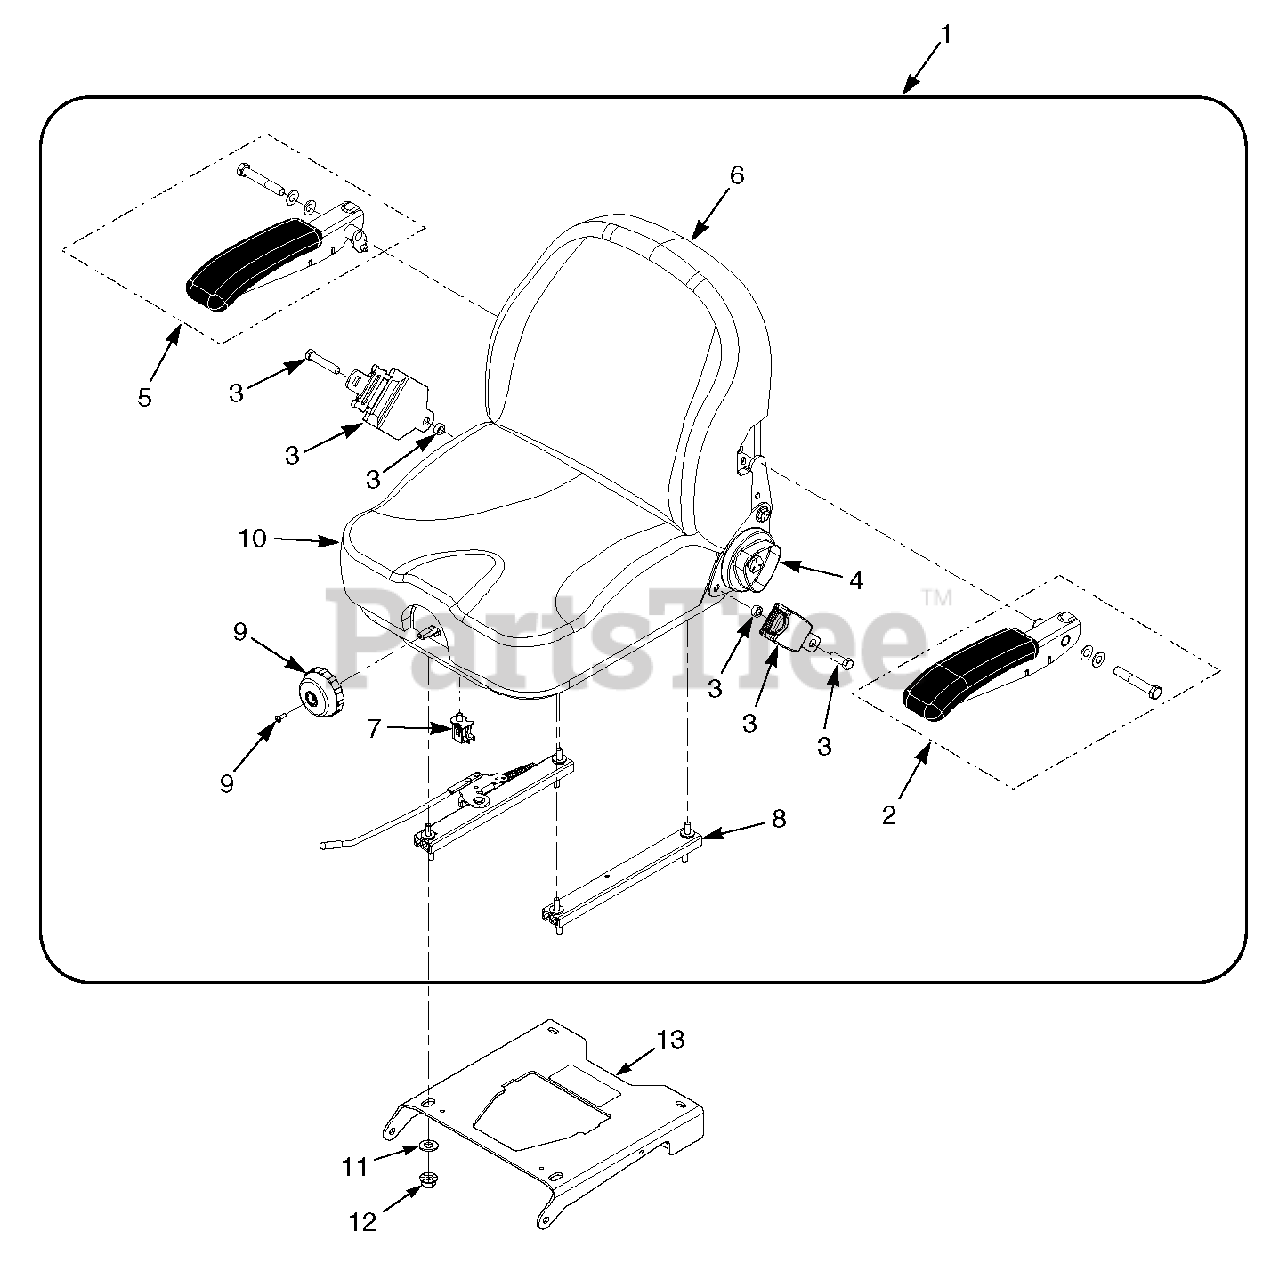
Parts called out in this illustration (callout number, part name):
1	Suspension Seat Assembly w/seat belt
2	Armrest Kit, LH
3	Seat Belt Kit
4	Recliner Knob Kit
5	Armrest Kit, RH
6	Back Cover
7	Seat Switch
8	Track Kit
9	Suspension Knob Kit
10	Seat Cushion
11	Flatwasher, 3/8-.391 x .938 x .105
12	Nut, Serrated Flange 5/16-18
13	Seat Plate Weldment w/Decal
